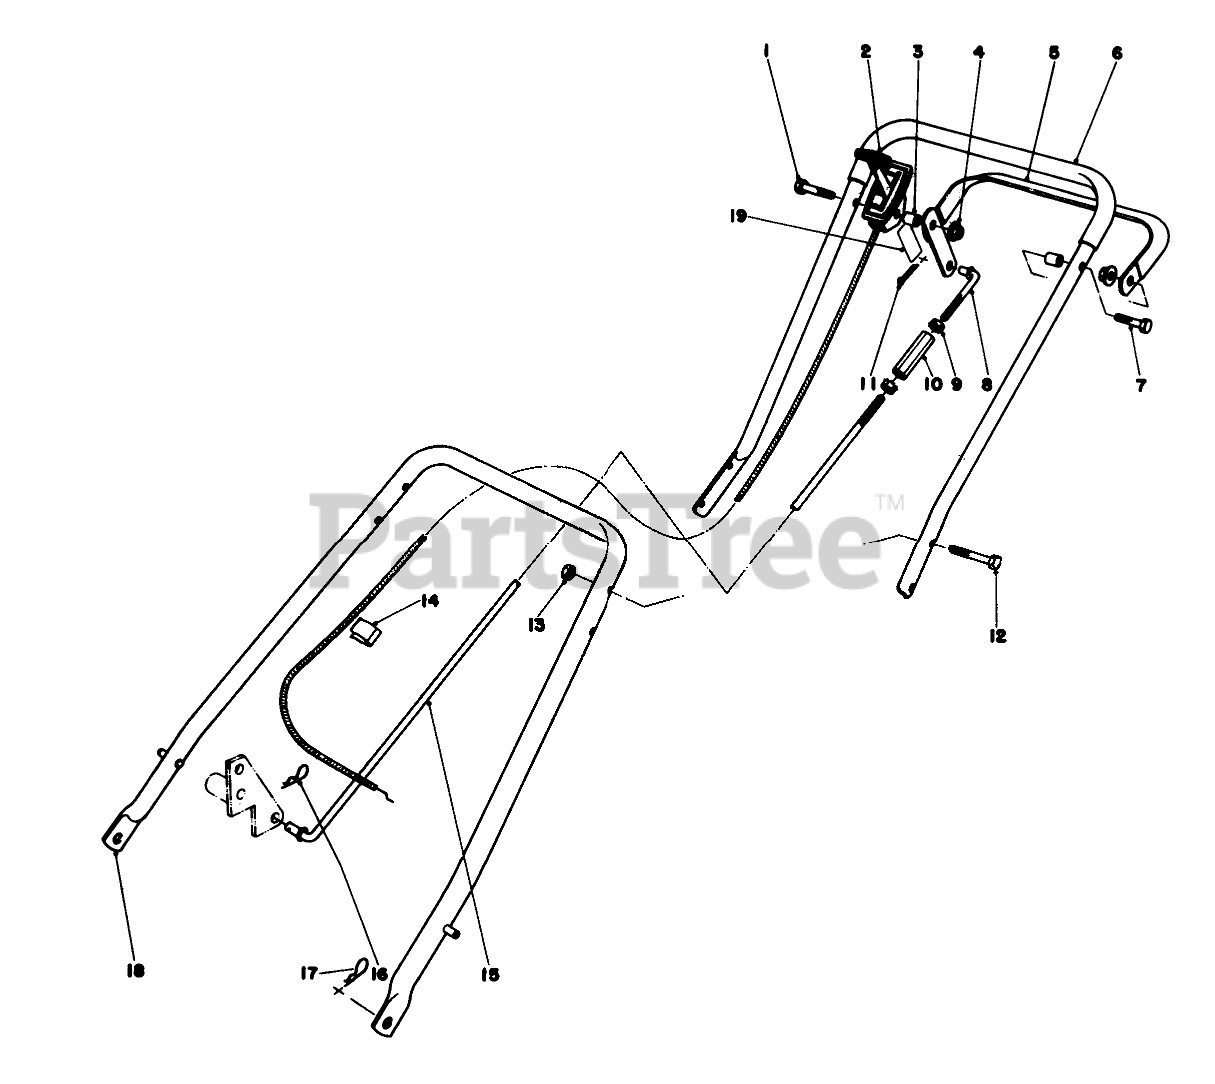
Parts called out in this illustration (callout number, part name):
1	SCREW-HH
2	THROTTLE CONTROL
3	Spacer
4	NUT-LOCK, HHF
5	Control Bail
6	UPPER HANDLE
7	SCREW-HH
8	LINK CONTROL ROD
9	NUT-KEPS
10	CONTROL ROD SLEEVE
11	PIN-COTTER
12	SCREW-HH
13	NUT-LOCK
14	Clamp
15	CONTROL ROD
16	HAIRPIN COTTER
17	PIN-COTTER, HAIR
18	LOWER HANDLE WA
19	Decal Traction Control
